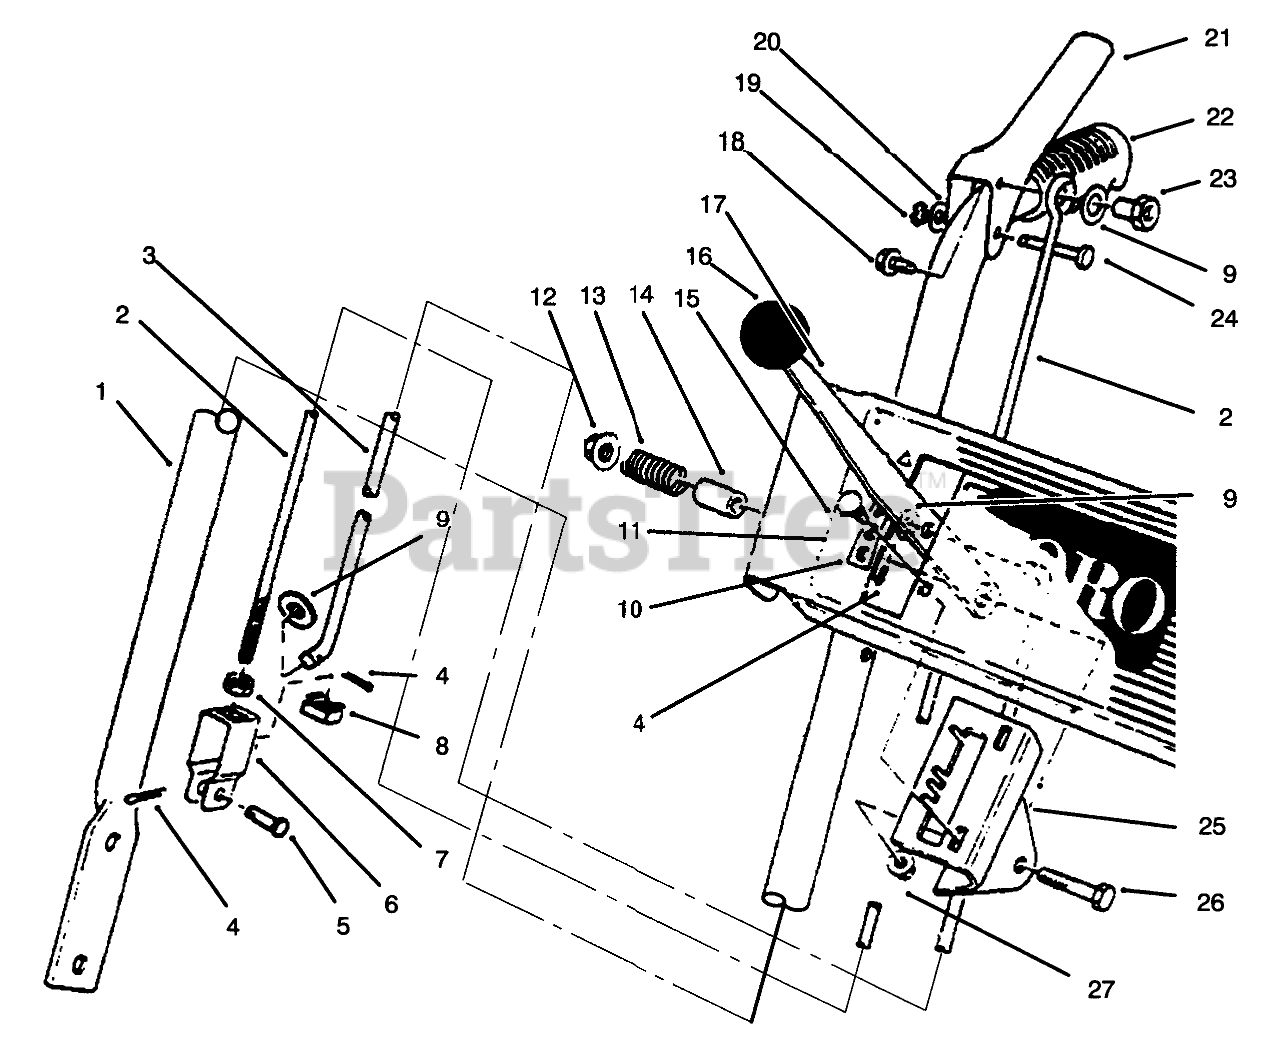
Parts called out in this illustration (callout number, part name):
1	Handle-Right
2	LINK-UPPER
3	ROD-SELECTOR, SPEED
4	PIN-COTTER
5	PIN-CLEVIS
6	CLEVIS
7	NUT-JAM
8	NUT-RETAINED
9	WASHER-PLAIN
10	ESCUTCHEON PLT B
11	DECAL - ESCUTCHEON
12	NUT-HF
13	SPRING
14	SPACER
15	SCREW-CARR
17	Selector-Speed
18	SCREW-HHF
19	RING-CLIP
20	WASHER-FLAT
21	HANDLE-CONTROL
22	GRIP-HANDLE
23	POST-MOUNTING, LINKAGE
24	PIN-LEVER, CONTROL
25	Mount-Speed Selector
26	SCREW-HH
27	NUT-HF
